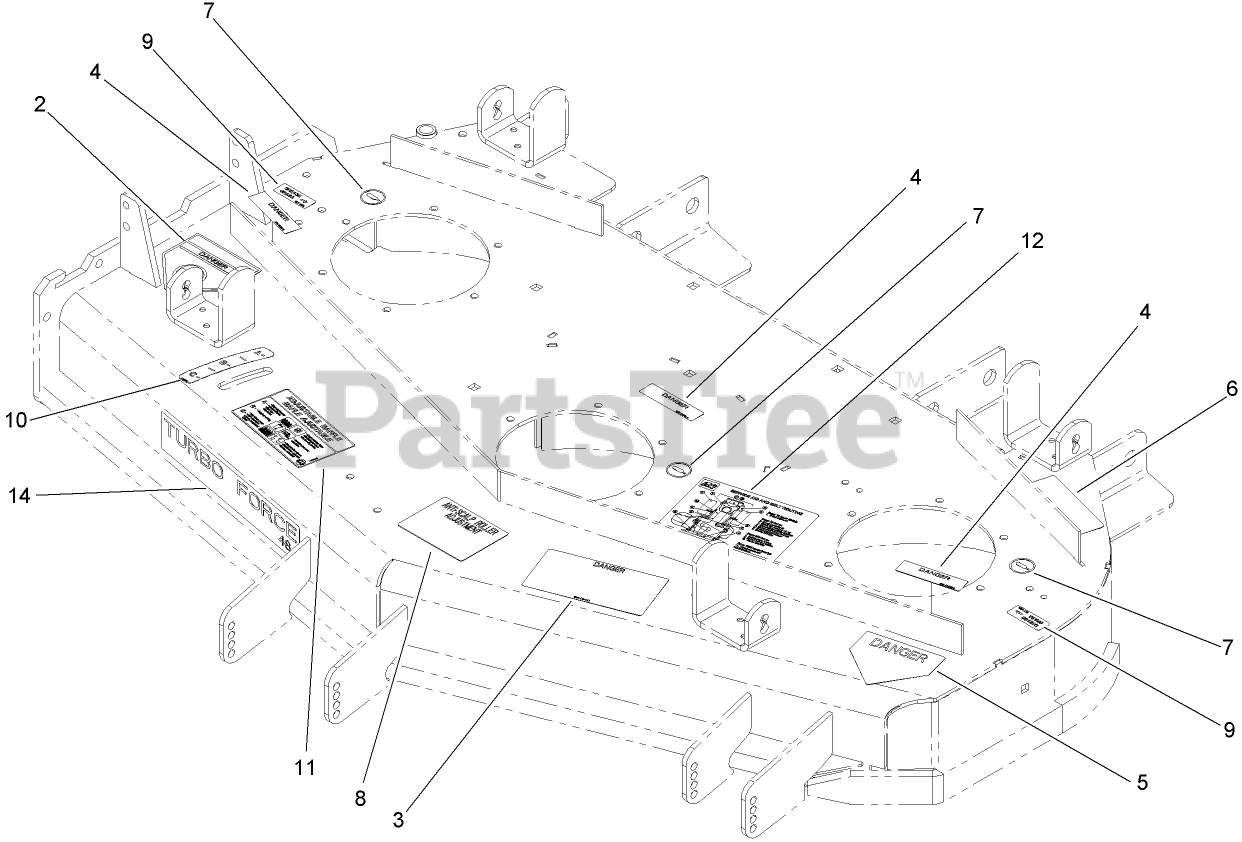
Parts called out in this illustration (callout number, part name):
2	DECAL-DANGER
3	DECAL-DANGER, THROWN OBJECT
4	DECAL-COVER, MISSING
5	DECAL-DANGER
6	DECAL-TORQUE
7	DECAL-GREASE
8	DECAL-SCALP, ANTI
9	Decal-Grease
10	DECAL-SETTING, BAFFLE
11	DECAL-ADJUSTMENT, BAFFLE
12	DECAL-AID, SERVICE
